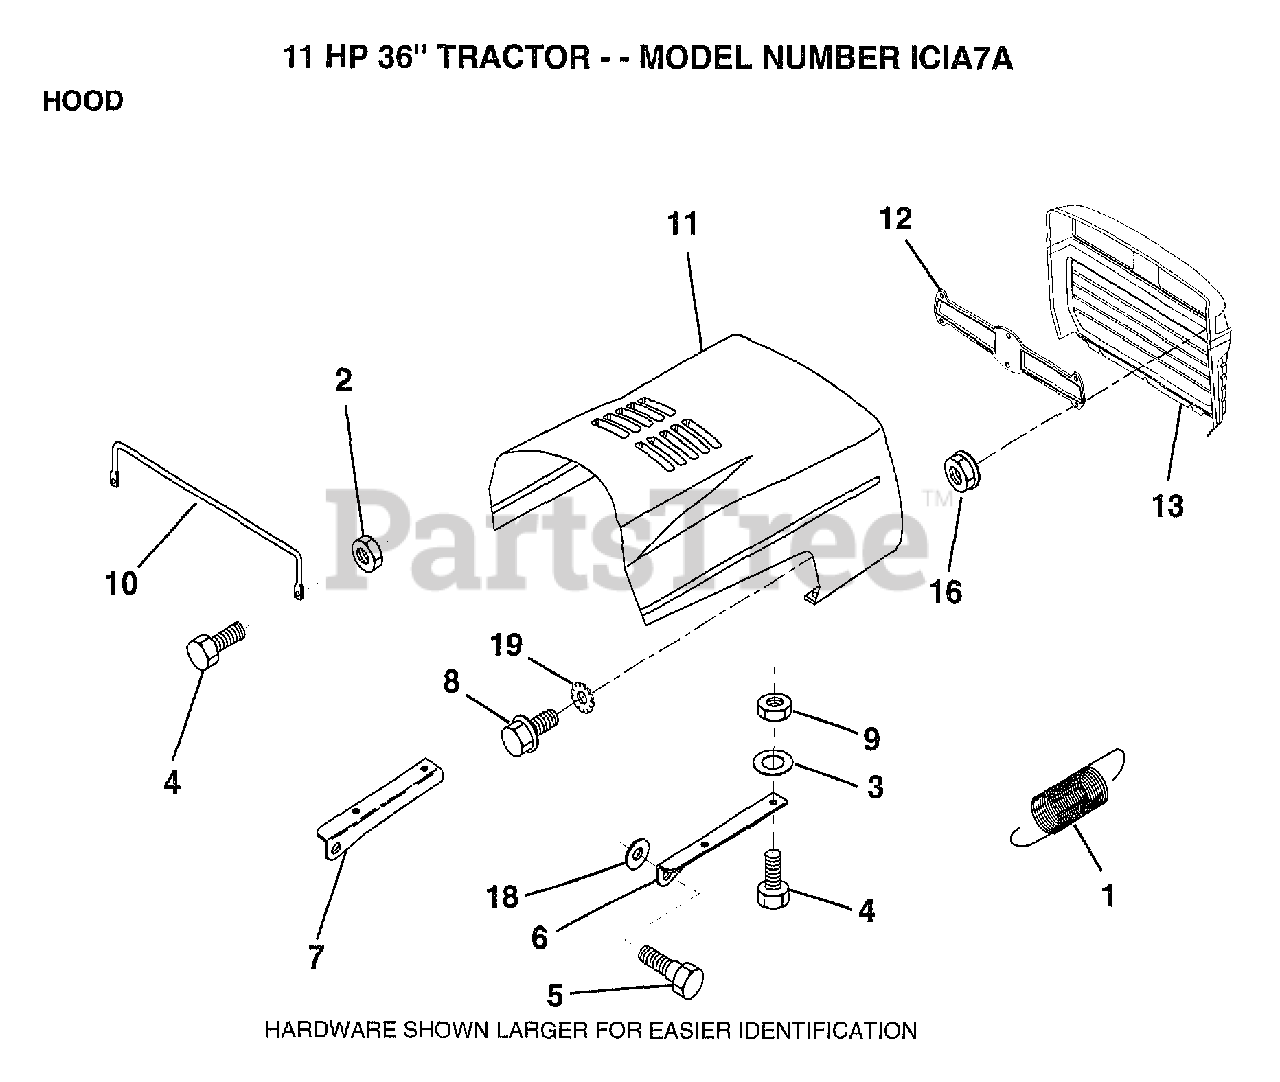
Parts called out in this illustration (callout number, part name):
1	EXT SPRING
2	NUT
3	WASHER
6	BRKT HOOD RH
7	BRKT HOOD LH
9	NUT
10	"BRACE,HOOD"
11	HOOD
13	GRILL (BLACK)
16	NUT
18	WASHER
19	LOCKWASHER GT
